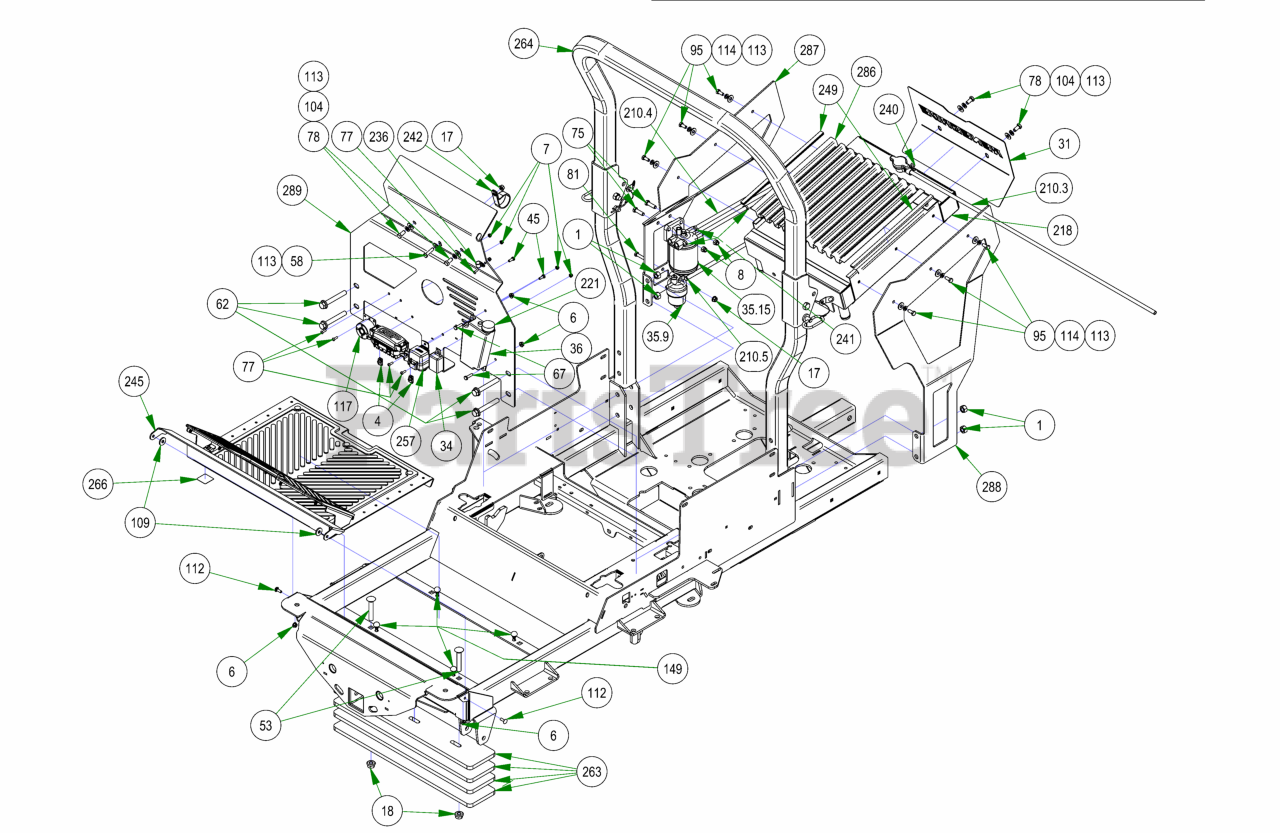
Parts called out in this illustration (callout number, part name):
1	1/2-13 HEX 2-WAY REVERSIBLE CENTER LOCKNUT Grade B ZINC
4	1/4-20 Cage Nut
6	1/4-20 NYL INSERT FLANGE LOCKNUT ZINC
7	10-24 NYLON INSERT LOCKNUT ZINC
8	3/8-16 NYLON INSERT LOCKNUT ZINC
17	5/16-18 NYLON INSERT FLANGE LOCKNUT ZINC
18	1/2-13 NYLON INSERT FLANGE LOCKNUT ZINC
31	2019 Diesel Upper Rear Cover - Black
34	Auto Shut Down for Cat Diesels
35.9	FUEL PRE-FILTER
35.15	Fuel Filter
36	overflow Reservoir- 27Kaw & 28/35Hp Diesel
45	M6-1.0 X 16MM DIN 933 HEX TAP BOLT (CL 8.8) ZINC
53	1/2-13 x 3 Carriage Bolt Grade 5
58	5/16-18 X 1-1/4 HEX C/S (GR.5) ZC
62	1/2-13 X 3-1/2 HEX FLANGE BOLT (GR.8) ZINC
67	1/4-20 X 1 HEX CAP SCREW (GR.5) ZINC
75	3/8-16 X 1-1/4 HEX CAP SCREW (GR.5) ZINC
77	10-24 X 5/8 BUTTON SOCKET CAP SCREW 18-8 STAINLESS STEEL
78	3/8-16 X 3/4 HEX CAP SCREW (GR.5) ZINC
81	5/16-18 X 2-1/2 HEX CAP SCREW (GR.5) ZINC
95	5/16-18 X 3/4 HEX CAP SCREW (GR.5) ZINC
104	3/8 SPLIT LOCKWASHER ZINC
109	.360 ID X .983 OD X .120 THICK FLAT WASHER NYLON
112	1/4-20 X 3/4 CARRIAGE BOLT (GR.5) ZINC
113	5/16 USS FLAT WASHER (7/8 OD) ZINC
114	5/16 SPLIT LOCKWASHER ZINC
117	Heat Warning Piezo Buzzer
149	2023 Floor Board Rubber Bumper
210	2022 Renegade Diesel Fuel Line Assembly
210.3	5/16 Clear Hose
210.4	5/16" fuel line hose
210.5	5/16 Fuel Line Clamp
218	2019 Diesel Radiator Kit
221	Reservoir Tank Cap-Overflow
234	2022 Horizontal Diesel Frame
236	3/8 Cable Clamp-Black Nylon
240	5/8 Hose Clamp
241	2 EAR CLAMP 12.5mm-15mm
242	Diesel Clamp 1 3/4" Vinyl
245	R-Series Floorboard Assembly
249	Rubber Trim
257	2022 Renegade Diesel Wiring Harness
263	2019 Outlaw Counter Weight
264	2019 2X2 Folding ROPS
266	Patent Decal (Anti-Wobble)
286	Radiator Screen Diesel
287	2019 Diesel Radiator Mount - Right
288	2019 Diesel Radiator Mount - Left
289	2022 Diesel Radiator Mount
